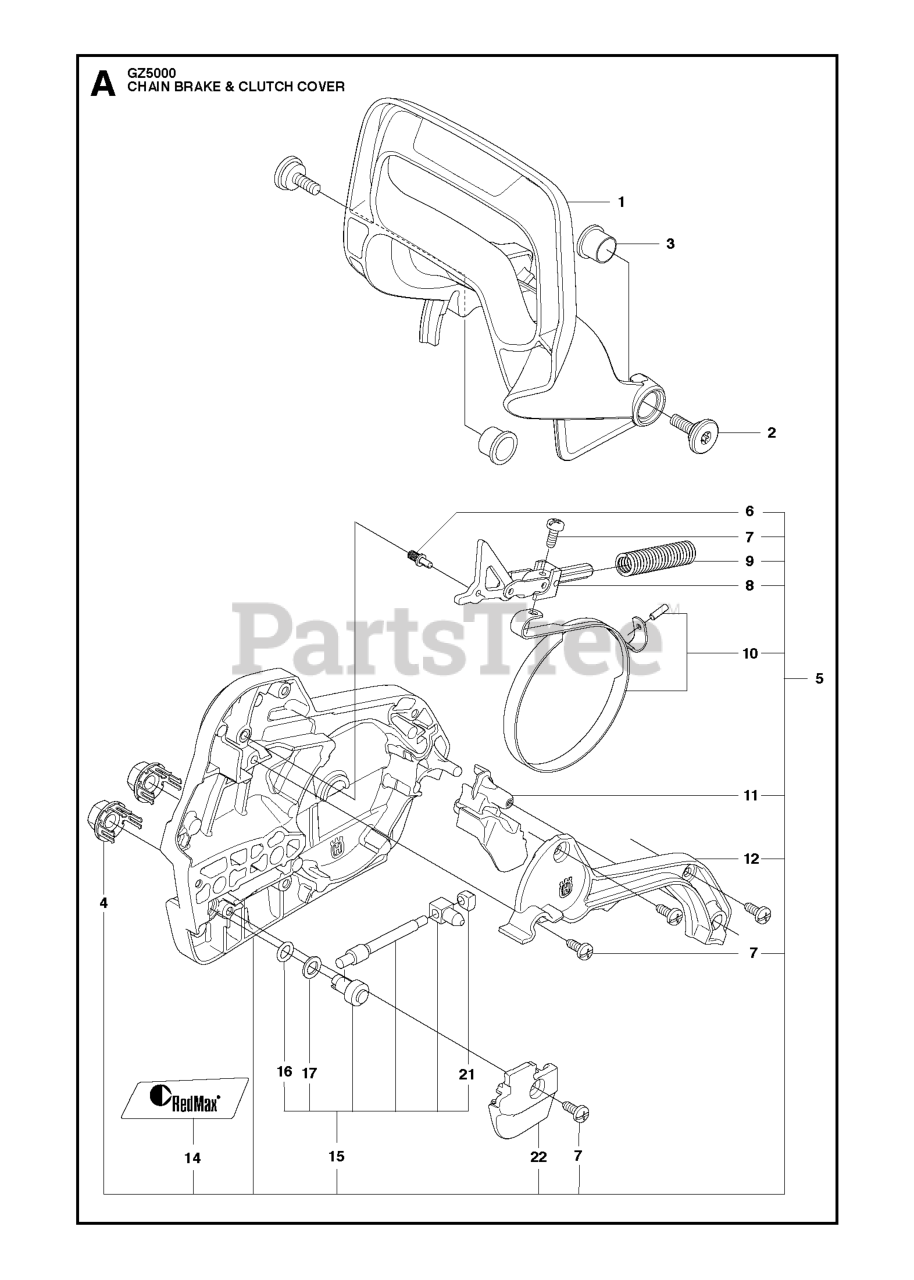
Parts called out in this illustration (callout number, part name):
1	HAND GUARD
4	NUT RETAINER ASSY
8	KNEE JOINT ASSY
10	BRAKE BAND
12	COVER BRAKE COVER JONSERED BLA
15	CHAIN TENSIONER KIT
17	WASHER STEEL
21	BEARING SLEEVE
22	CHAIN GUIDE JONSERED BLACK
